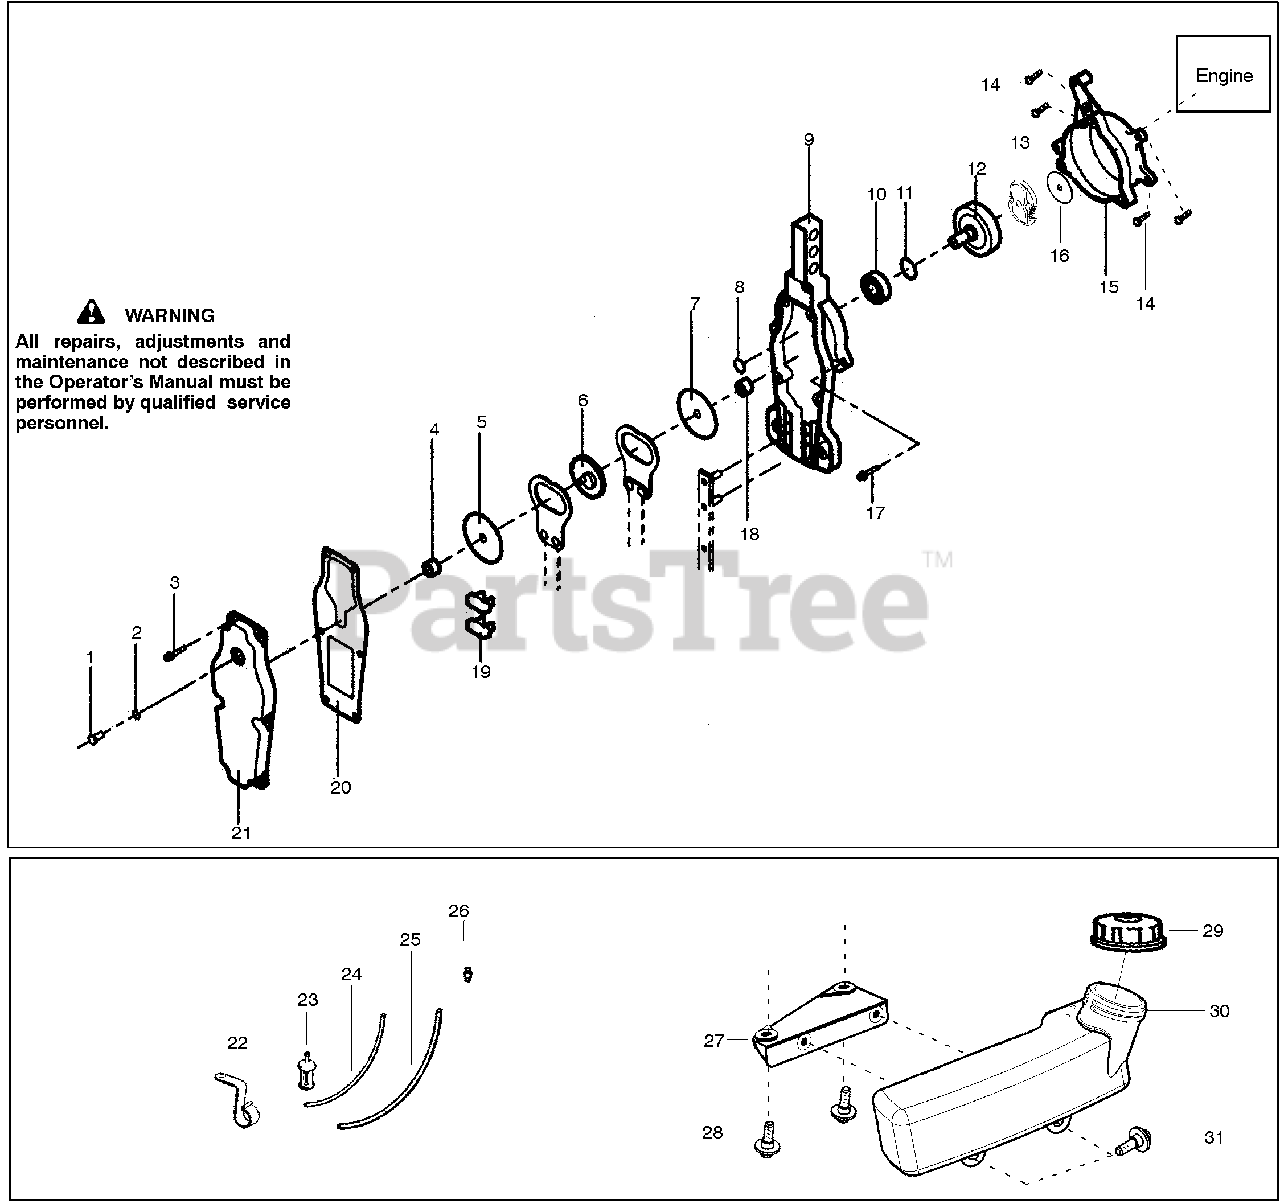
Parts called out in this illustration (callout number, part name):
2	O-ring
3	Socket Screw Flange
8	C-Snapring for Shaft
11	C-Snapring for Hole
12	Clutch Drum C.P.
13	Kit-Clutch Assy.
16	Washer-Clutch
17	Socket Screw Flange
21	Cam Case Cover
23	Assy-Fuel Pickup
24	Kit-Fuel Line (small)
25	Kit-Fuel Line(large)
26	Fitting-Fuel Line
28	Screw-Retainer
29	Assy-Fuel Cap
30	Assy-Fuel Tank
31	Screw-Retainer
